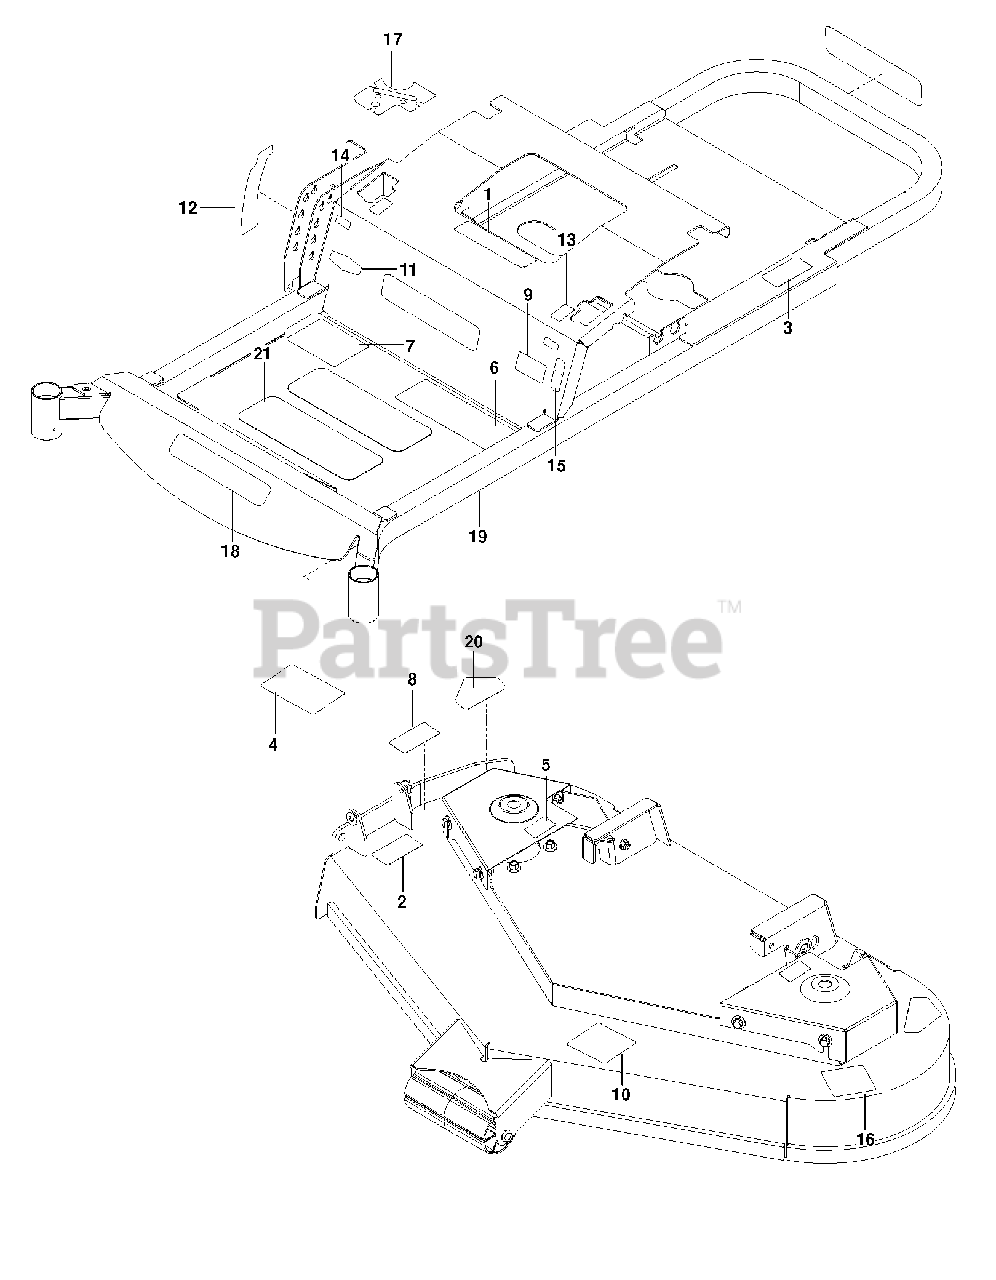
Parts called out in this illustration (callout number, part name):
2	DECAL, EURO SEVERING
3	DECAL, DO NOT MOUNT
4	DECAL, SERVICE
6	DECAL, SAFETY WARNING
7	DECAL, WARNING
8	DECAL, DANGER
9	DECAL, FLAG
10	DECAL, BELT ROUTING
20	DECAL, CPSC
21	ANTI-SKID PAD
